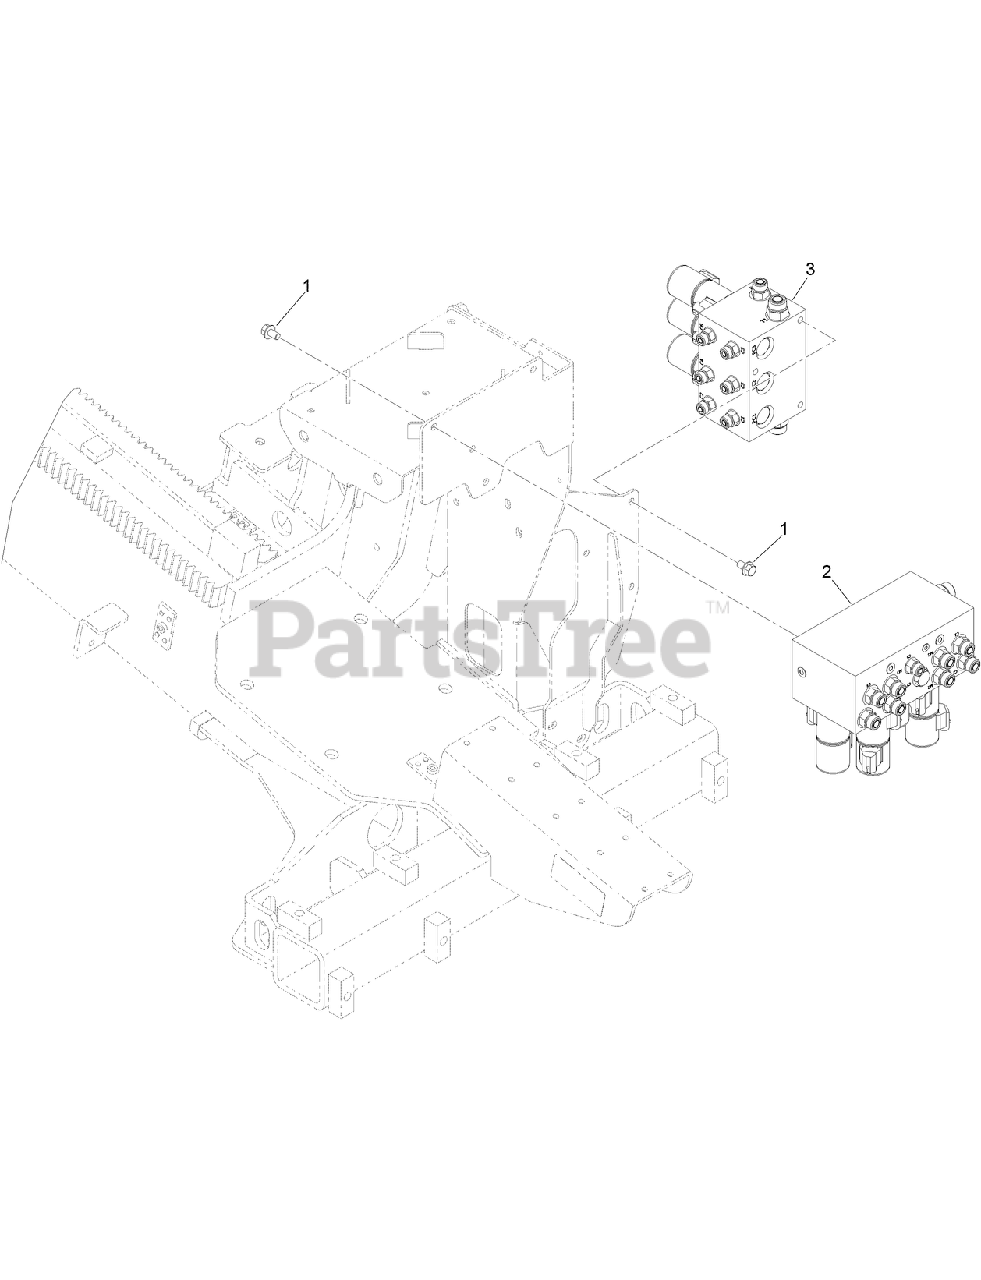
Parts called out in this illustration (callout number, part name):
1	SCREW-HHF
2	STAKE MANIFOLD ASM
3	WRENCH MANIFOLD ASM
